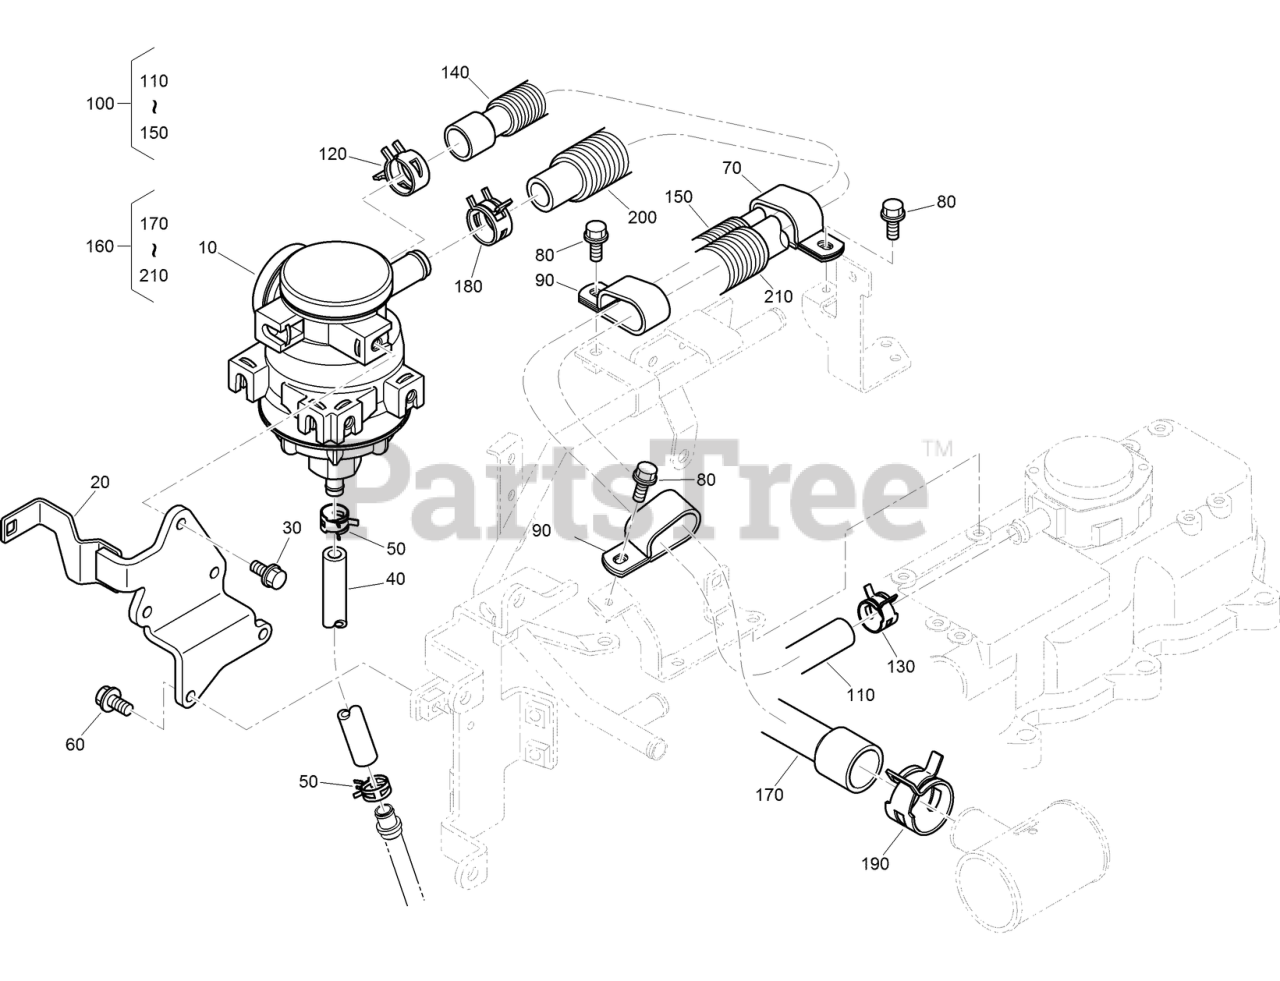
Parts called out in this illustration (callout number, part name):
10	SEPARATOR ASM
20	BRACKET-SEPARATOR
30	BOLT-FLANGE
40	TUBE-RETURN, OIL
50	CLAMP-HOSE
60	BOLT-FLANGE
70	CLAMP-HOSE
80	BOLT-FLANGE
90	CLAMP-HOSE
100	BREATHER 1 TUBE ASM
110	TUBE-BREATHER 1
120	CLAMP-HOSE
130	CLAMP-HOSE
140	TUBE-PIPE
150	TUBE-CORRUGATE
160	BREATHER 2 TUBE ASM
170	TUBE-BREATHER 2
180	CLAMP-HOSE
190	CLAMP-HOSE
200	TUBE-CORRUGATE
210	TUBE-CORRUGATE
